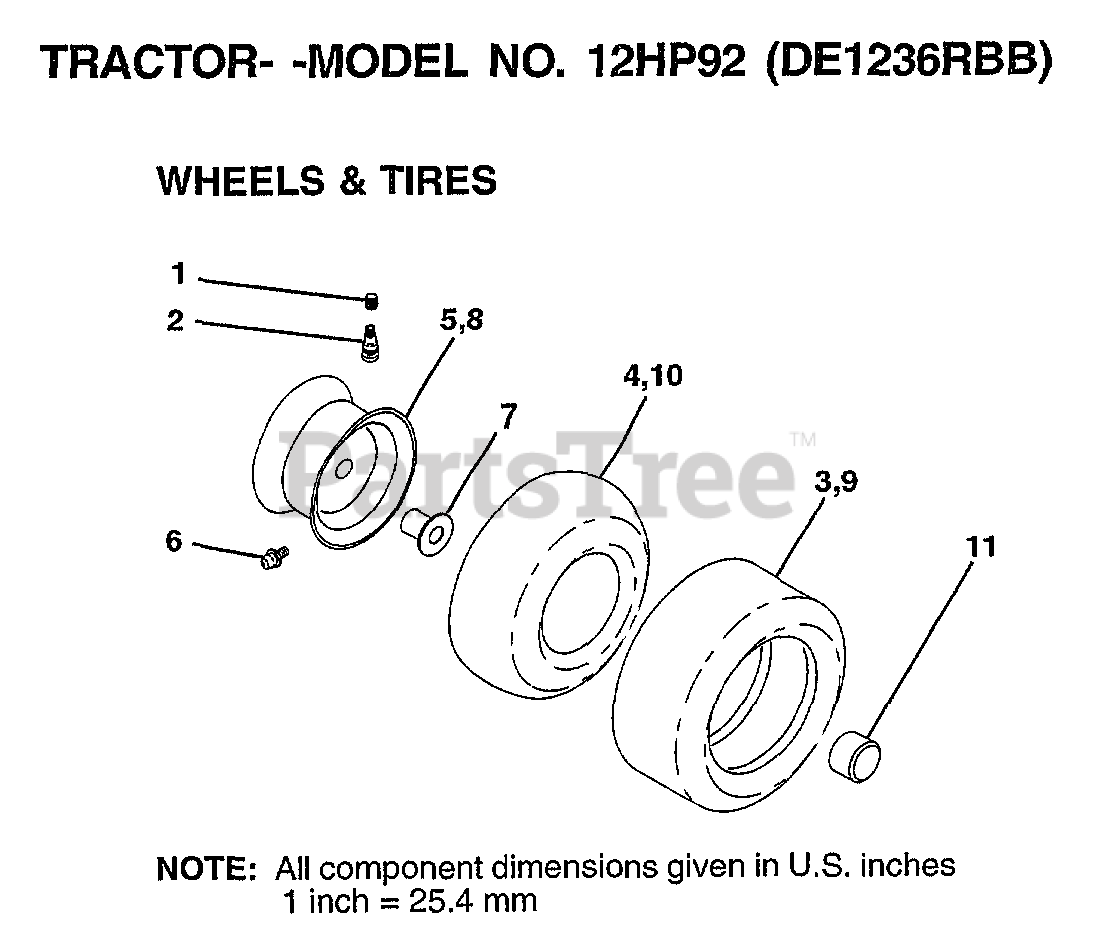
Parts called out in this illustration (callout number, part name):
1	VALVE CAP
2	VALVE STEM LT
4	TUBE.5.3/4.5/6
5	"RIM,FRT T"
6	FITTING LT
7	"FLANGE, BEARING"
8	"RIM 8"""
10	TUBE.18X9.5-8
11	HUB CAP
